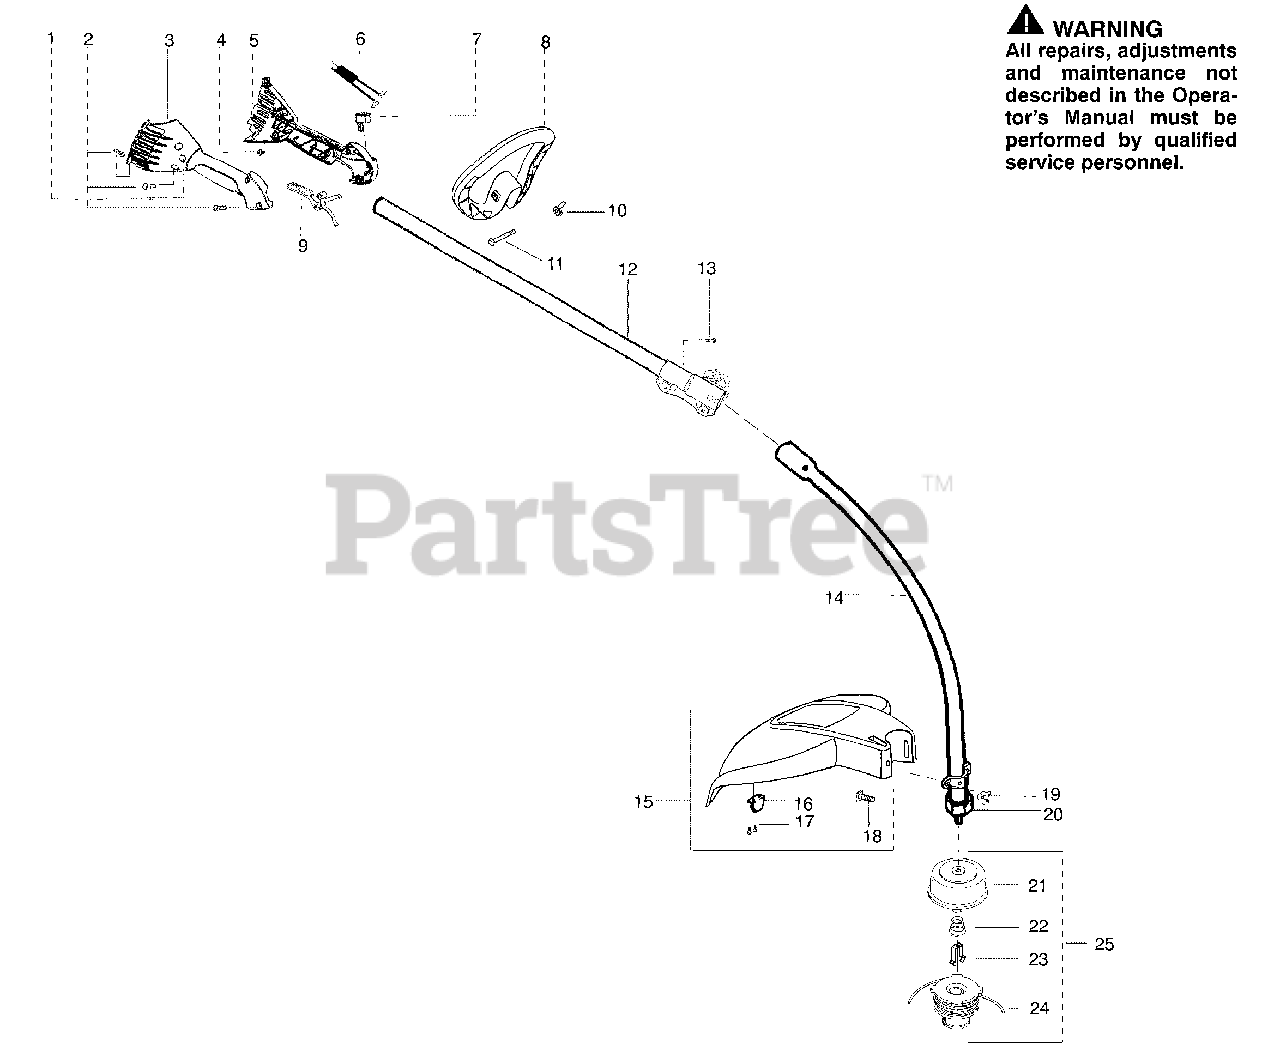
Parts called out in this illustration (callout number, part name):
1	Screw-alignment
3	Hsg.-Throttle right
4	Screw-Cable Retention
5	Hsg.-Left throttle
6	Assy-Wire
7	Kit-Switch
8	Handle-Assist
9	Trigger-Throttle
10	Wingnut
12	Assy-Upper Shaft
14	Assy-Lower Shaft
15	Kit-Shield Assy.
16	Limiter-Line
19	Wingnut
21	Assy-Hub/Arbor
22	Spring-Return
23	Retainer-Spool
24	Accy-Wound Spool
25	Accy-Cutting Head
